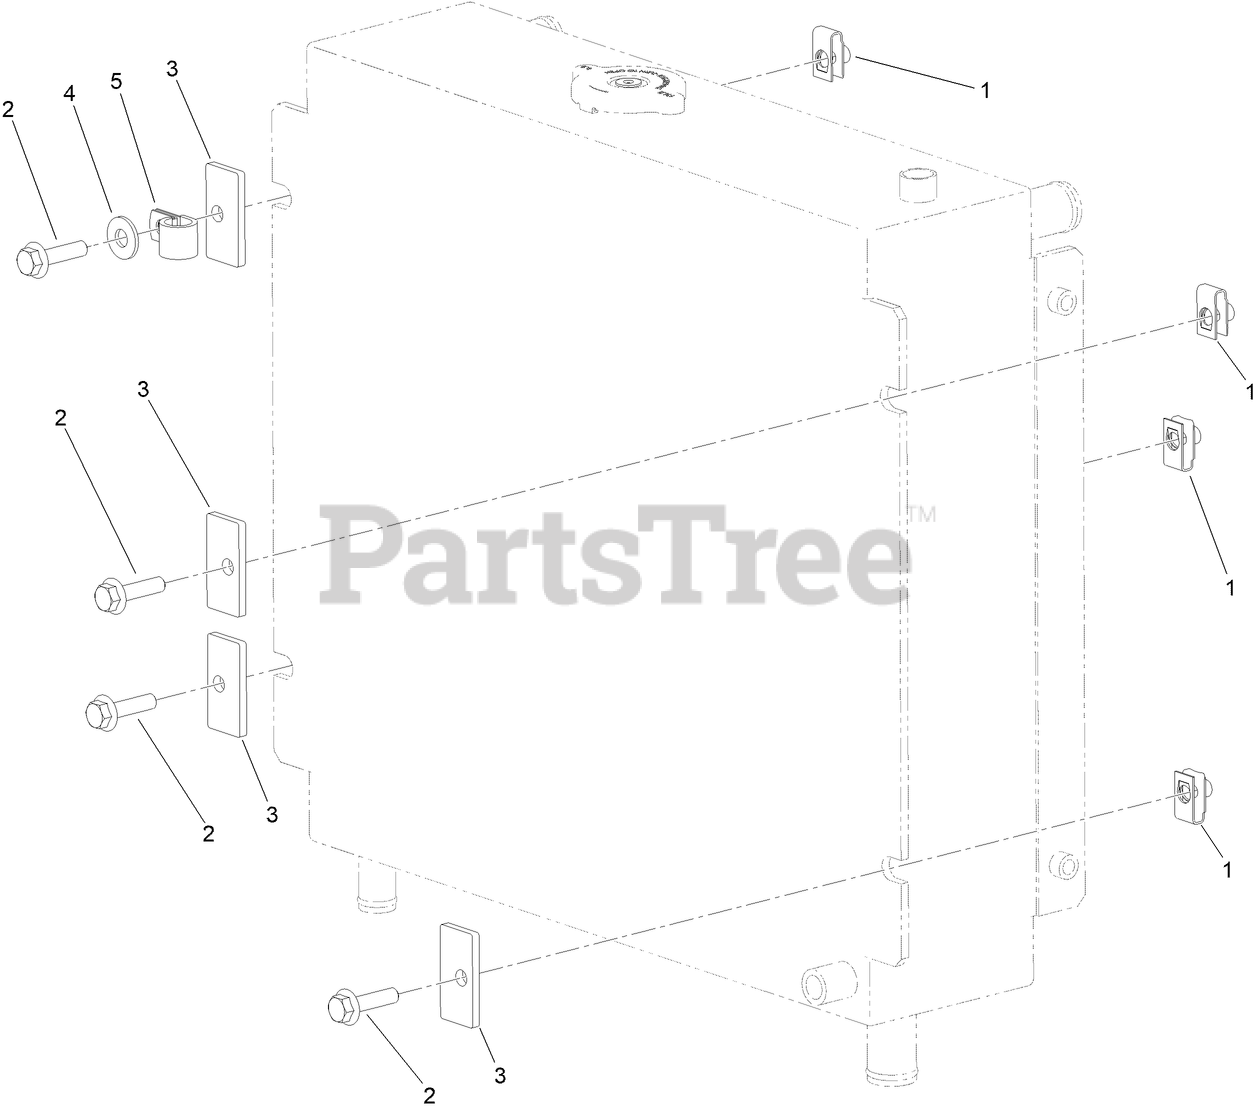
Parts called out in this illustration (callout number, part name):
1	NUT-CLIP, U
2	SCREW-HHF
3	WASHER-SQUARE
4	WASHER-FLAT
5	CLAMP-R
